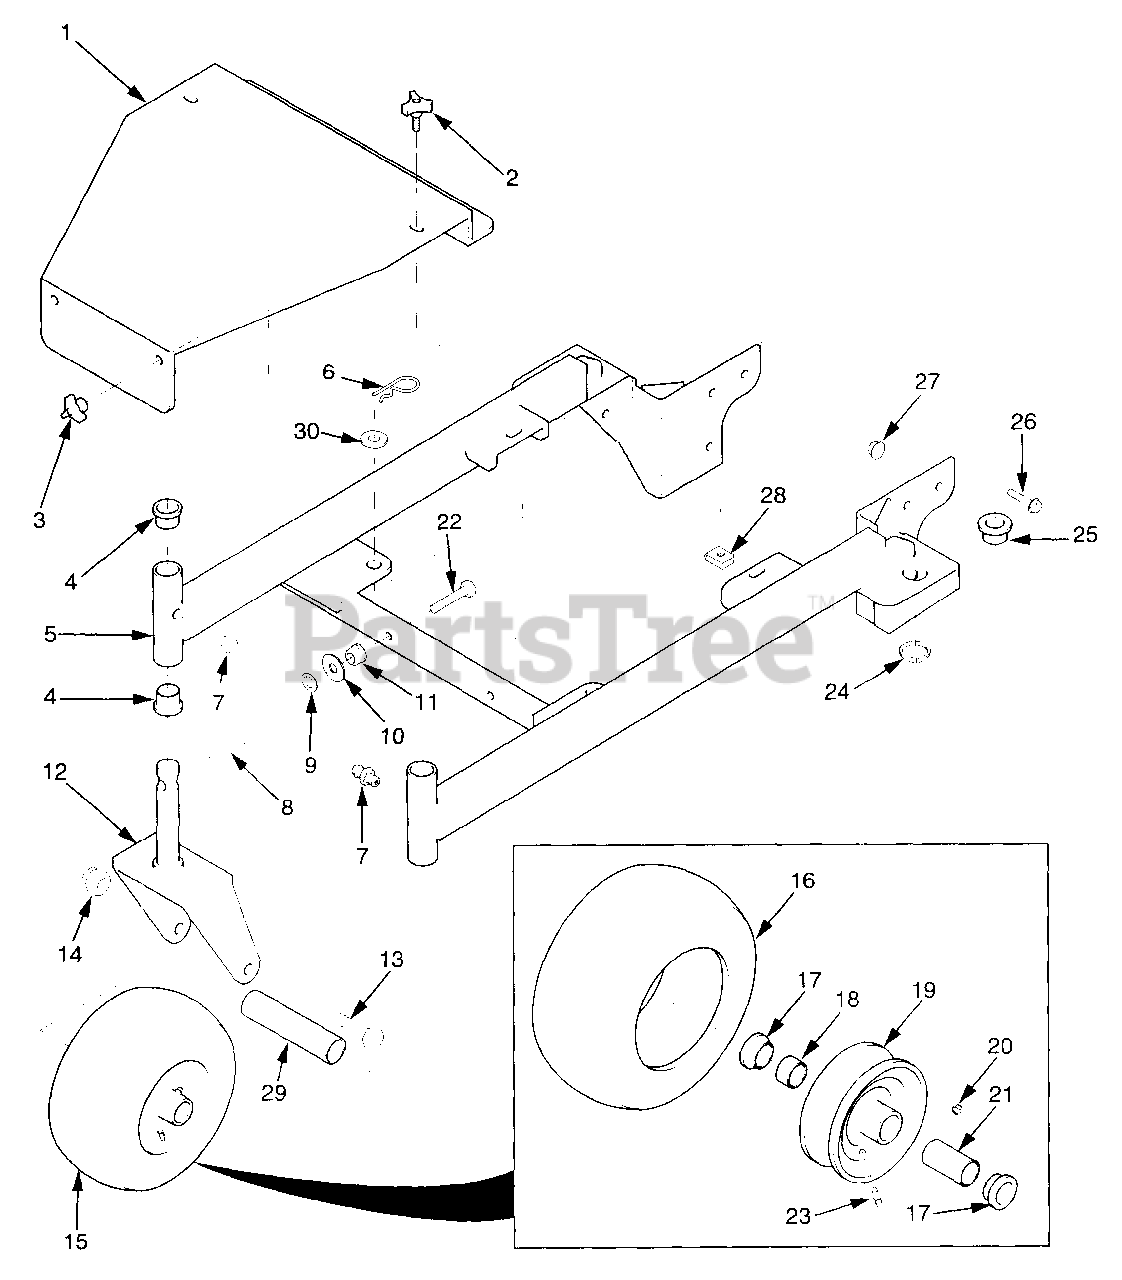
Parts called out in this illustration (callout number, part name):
1	Belt Cover With Decal
2	Knob With Stud
3	Knob, Deck Cover Mounting
4	Bushing, Caster
5	Frame Weldment, Deck Mounting - 36"
6	Hair Pin Cotter, .177 x 3.25"
7	Grease Fitting Str. 1/4-28 Self Tap
8	Quick Pin .438 Dia
9	Nut, Push-On - 3/8 Thd.
10	Flatwasher, 3/8 - (.391 x .938 x .105)
11	Nut, 3/8-16 Serrated Flange Hex Head
12	Yoke, Caster Wheel
13	Capscrew, Hex Head 1/2-13 x 6.50"
14	Locknut, 1/2-13 Elastic Stop
15	Wheel Assembly, Caster
16	Tire, 11 x 4.00-5
17	Retainer
18	Roller Bearing
19	Rim, 5.0 x 2.75 With Zerk & Valve
20	Grease Fitting Str.1/4-28
21	Roller Bearing .625 x 3.25"
22	Capscrew, Hex Head 3/8-16 x 2.25"
23	Tire Valve, Purchase Locally
24	Retaining Ring 1.50 Ext.
25	Bushing, Deck Adjustment Pin
26	Capscrew, Hex Head 7/16-14 x 1.0"
27	Nut, 7/16-14 Serrated Flange Hex
28	U-Nut, 3/8-16
29	Sleeve, Caster Wheel
30	Flatwasher, 5/8 - (.688 x 1.75 x .134)
